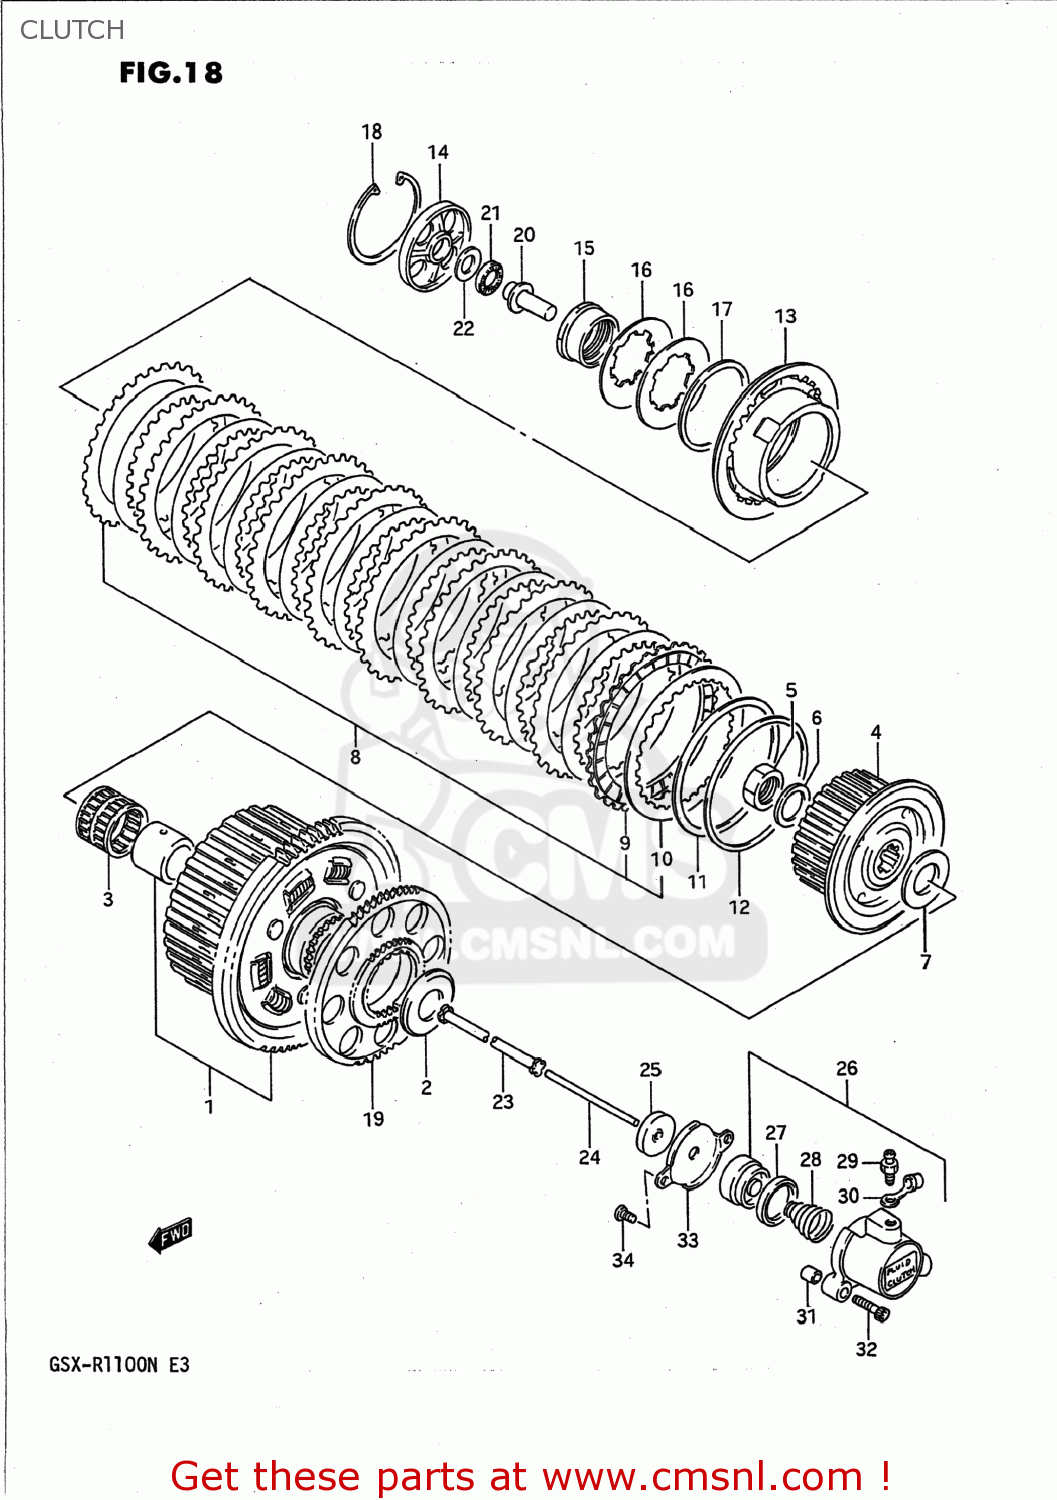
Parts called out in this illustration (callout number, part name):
1	GEAR ASSEMBLY,PRIMARY DRIVE
2	WASHER(25X54X2.5)
3	BEARING(35X40X35.8)
4	HUB,CLUTCH SLEEVE
5	NUT
6	WASHER
7	WASHER(25X50X2.5)
8	PLATE ASSEMBLY,CLUTCH
9	PLATE,CLUTCH DRIVE NO.1 (NAS)
10	PLATE,CLUTCH DRIVEN (NAS)
11	WASHER
12	SEAT,CL SLEEVE HUB WAVE WASHER
13	DISC,CLUTCH PRESSURE
14	LIFTER,CLUTCH PRESSURE DISC
15	HOLDER,CLUTCH SPRING
16	WASHER
17	SEAT,CLUTCH SPRING
18	CIRCLIP
19	GEAR,GENERATOR DRIVE
20	PIECE,CLUTCH PUSH
21	BEARING(15X28X2)
22	WASHER
23	ROD,CLUTCH
24	ROD,CLUTCH PUSH
25	SEAL,OIL(6X34X5.5)
26	CYLINDER,CLUTCH RELEASE
27	CUP
28	SPRING,CLUTCH CYLINDER
29	BLEEDER
30	CAP,BLEEDER
31	PIN
32	BOLT
33	PLATE,CLUTCH PUSH ROD
34	SCREW
